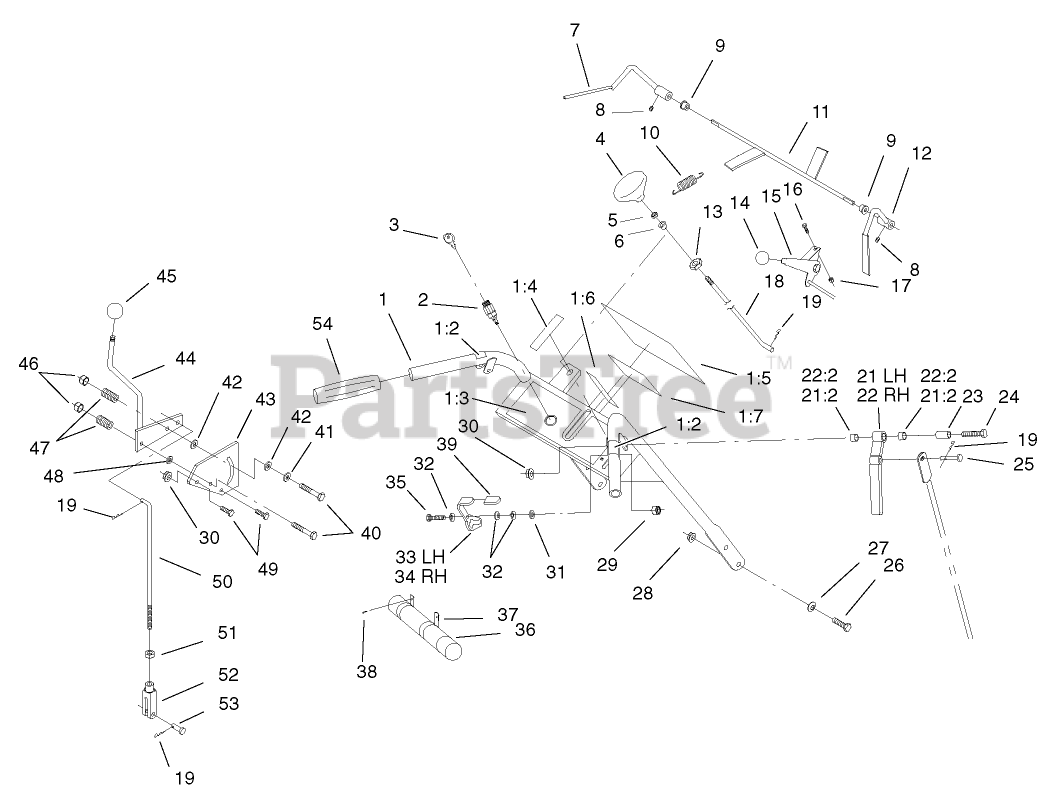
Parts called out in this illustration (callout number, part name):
1	HANDLE ASM
1:2	DECAL-LOCK, NEUTRAL
1:3	DECAL-WARNING
1:4	DECAL-THROTTLE
1:5	DECAL-PROLINE
1:6	DECAL-ENGAGE, DECK
1:7	DECAL-CAUTION, BRAKE
2	SWITCH & KEY (INCLUDES NUT & WASHER)
3	KEY-IGNITION
4	Knob-Push / Pull
5	NUT-JAM
6	Bearing-Nylon
7	LEVER-LH
8	SCREW-SET
9	BUSHING-NYLON
10	SPRING-EXTENSION
11	ROD-CONTROL, OPERATOR PRESENCE
12	LEVER-RH
13	NUT-PUSH
14	KNOB-BALL
15	THROTTLE CABLE ASM
16	BOLT-CARR
17	NUT-LOCK, NI
18	Linkage-Blade
19	PIN-COTTER
21	LH Drive Lever ASM
21:2	BUSHING-SLEEVE
22	RH Drive Lever ASM
22:2	BUSHING-SLEEVE
23	Bushing-Lever, Drive
24	SCREW-HH
25	Pin-Clevis
26	SCREW-HH
27	WASHER-BELLEVILLE
28	NUT-HHF, WHIZ
29	NUT-LOCK, NI
30	NUT-HF
31	WASHER-FLAT
32	WASHER-SPRING
33	LATCH-LEVER, LH DRIVE
34	LATCH-LEVER, RH DRIVE
35	SCREW-HH
36	TUBE-MANUAL
37	CLAMP-R
38	SCREW-HWHTF
39	GRIP-LATCH
40	SCREW-HH
41	Washer-Friction
42	Washer-Friction
43	PLATE-LEVER, SHIFTER
44	LEVER-SHIFT
45	KNOB-BALL
46	NUT-LOCK, NI
47	SPRING-COMPRESSION
48	WASHER-PLAIN
49	SCREW-HH
50	Rod-Control, Speed
51	NUT-JAM
52	YOKE-ADJUSTABLE
53	PIN-CLEVIS
54	Grip-Handle
